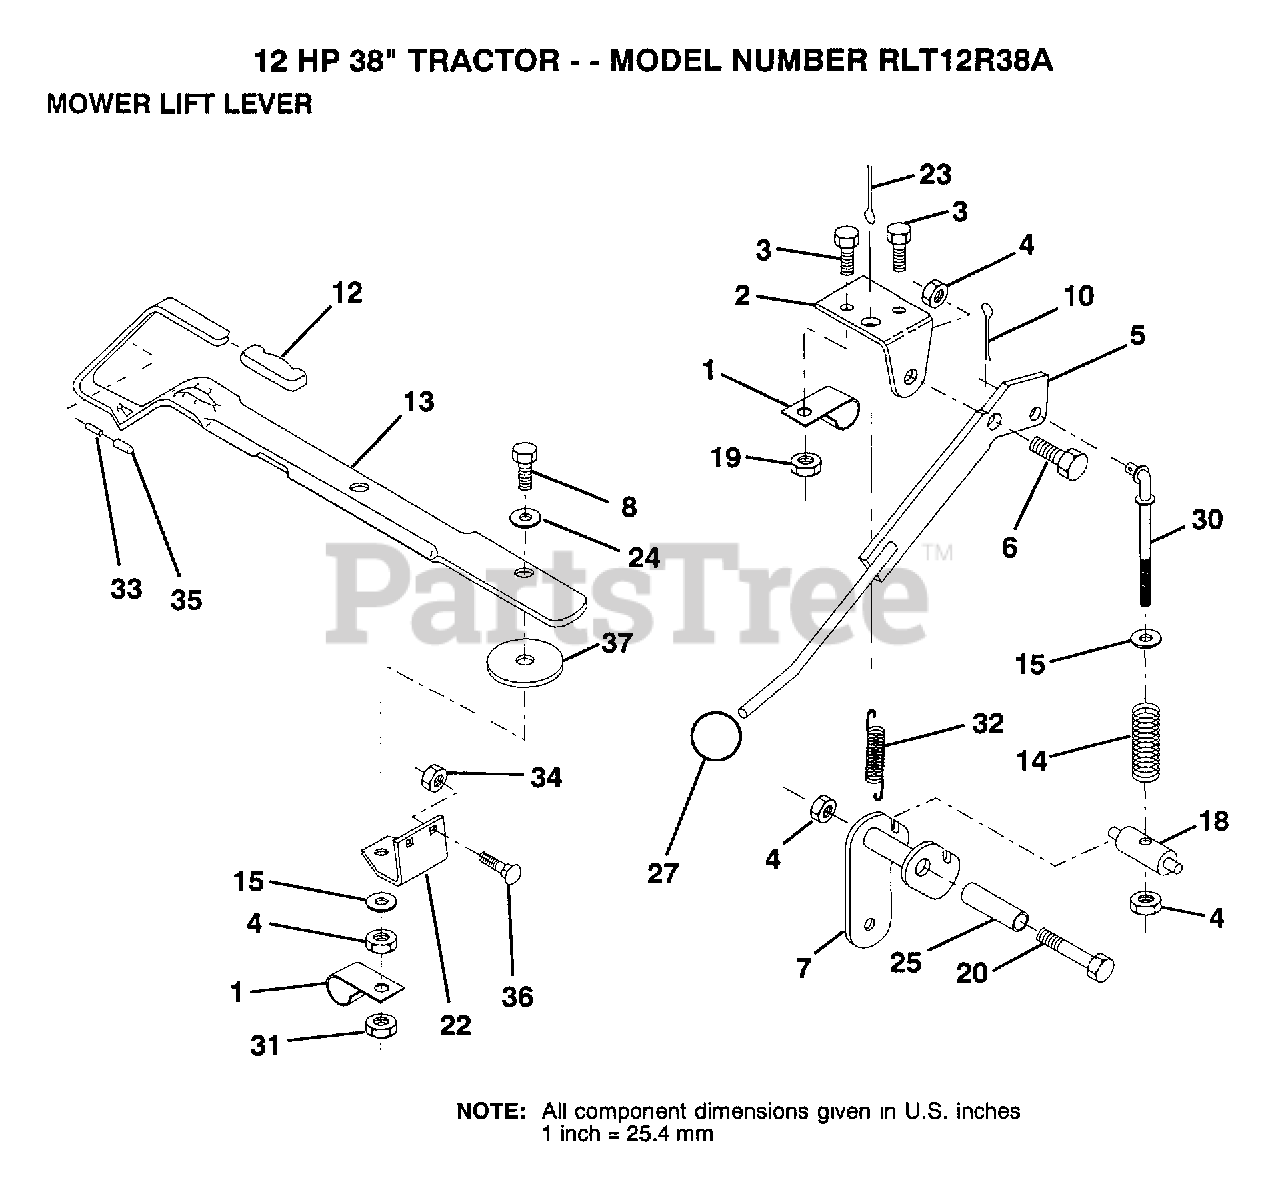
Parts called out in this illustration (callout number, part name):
1	"CLIP,INSULATOR"
2	BRKT CLUTCH
3	BOLT
5	CLUTCH LEVER AS
6	"BOLT, SHOULDER LT"
7	MWR CLUT ARM ASM
8	BOLT
10	COTTER PIN
12	LIFT LEVER HANDLE
13	LIFT HANDLE ASM
14	COMP CLUTCH SPRNG
15	WASHER HYT
18	TRUNNION
20	BOLT
22	LIFT LEVER BRKT
24	WASHER
25	TUBE SPACER
27	KNOB
30	ROD TENSION CLUTC
31	LOCKNUT
32	SPRING EXT
35	VINYL CAP RED
36	BOLT
37	WASHER T
